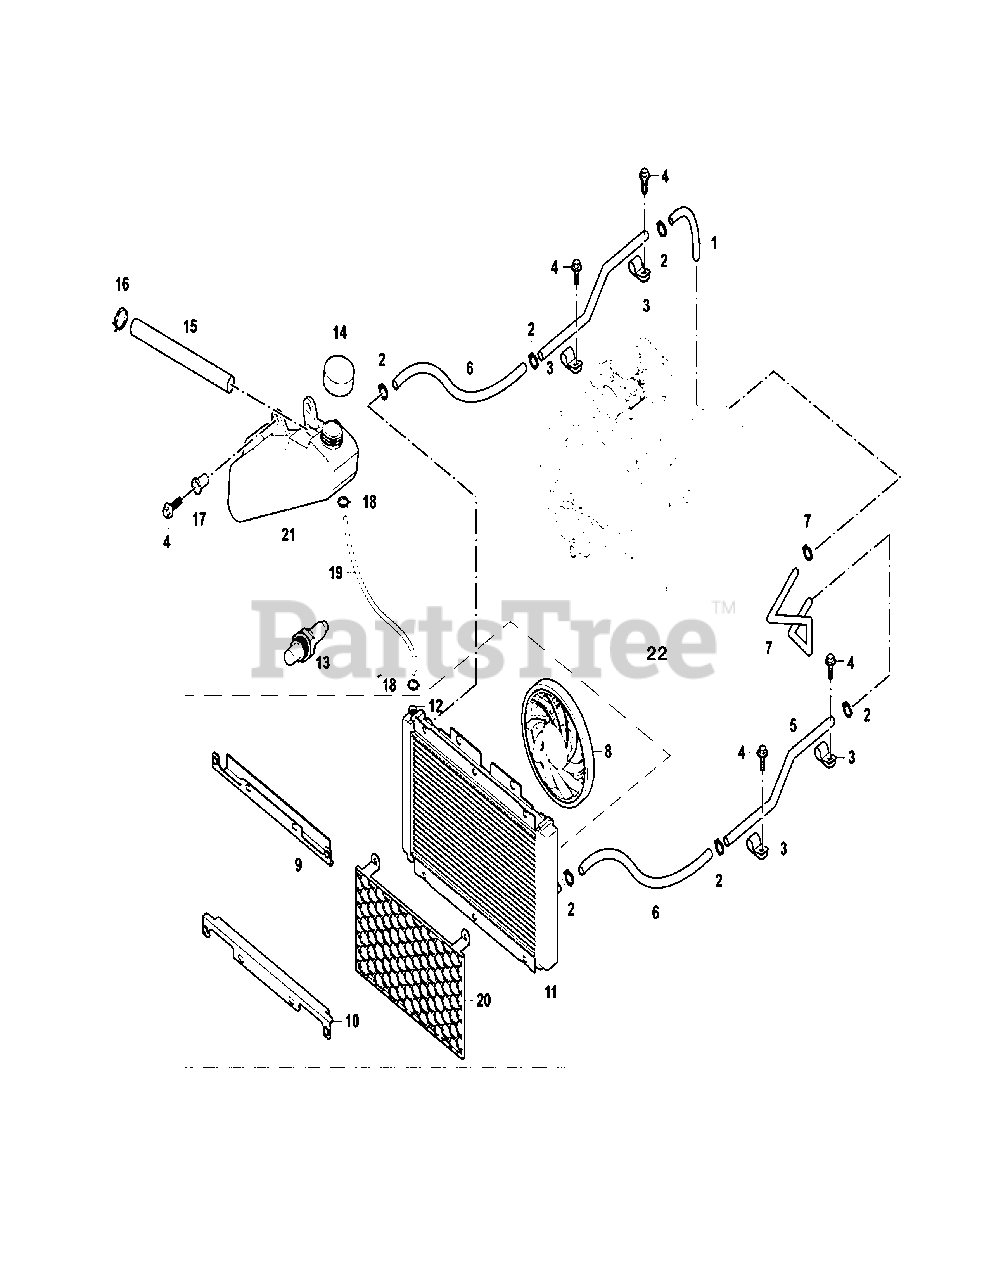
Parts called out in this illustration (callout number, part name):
1	Water Pipe C
2	Clamp20-32
3	Clip , metal water pipe
4	Hexagon Flange Bolt M6×16
5	Metal Water Pipe
6	Water Pipe A
7	Water Pipe B
8	Radiator Fan Assy
9	Installation Bracket I, Oil Cooler
10	Installation Bracket II, Oil Cooler
11	Cooling Tank
12	Cap, Radiator
13	Water Temperature Sensor
14	Secondary Water Tank Cover
15	Reservoir Tank Pipe II 7×11×750
17	Bushing 6.5×9×22×6.5
18	Clip9
19	Reservoir Tank Pipe I 5×9×500-30
20	Radiator Cover
21	Auxiliary Water Tank Assy
22	Cooling Fan
